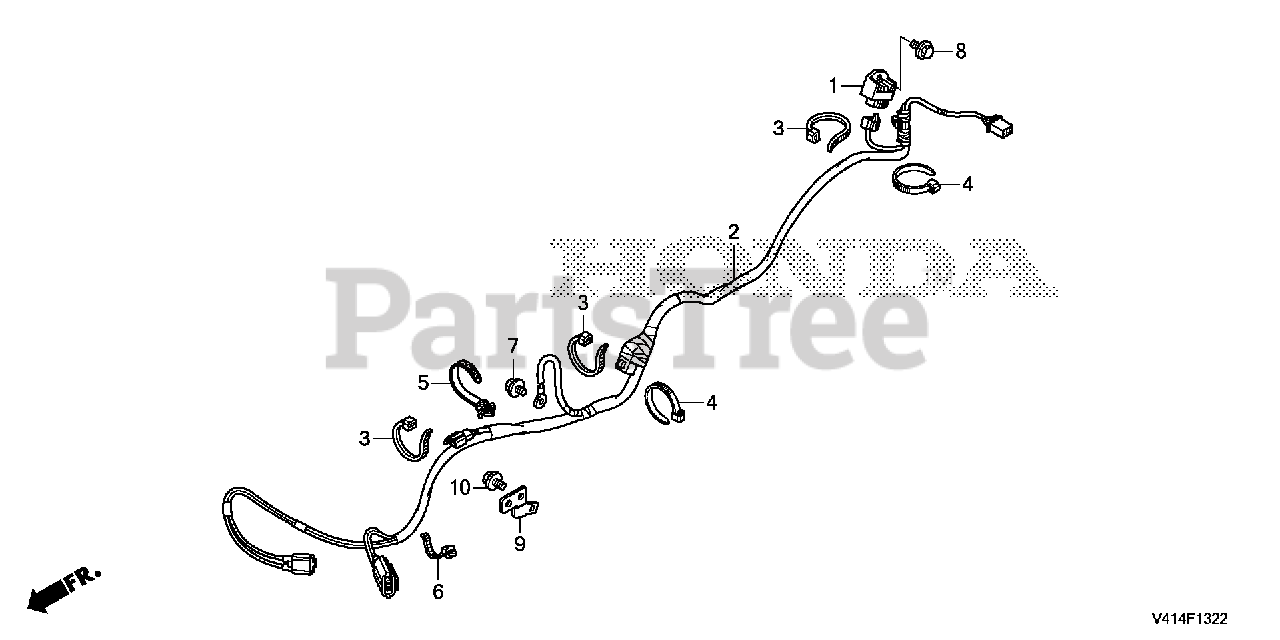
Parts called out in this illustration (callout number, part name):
2	WIRE HARNESS ASSY., MAIN
3	BAND, WIRE (95MM)
4	BAND, WIRE (165MM) (BLACK)
5	STRAP, CABLE (118MM) *NH1L* (Honda Code 1170653). (BLACK)
6	CLIP, HARNESS BAND (145MM) (BLACK)
7	BOLT, FLANGE (6X12) (CT200)
7	BOLT, FLANGE (6X10)
8	BOLT, FLANGE (6X12) Use up to Engine SN 1543277.
9	BASE, CLIP
10	BOLT, FLANGE (6X12) (CT200)
